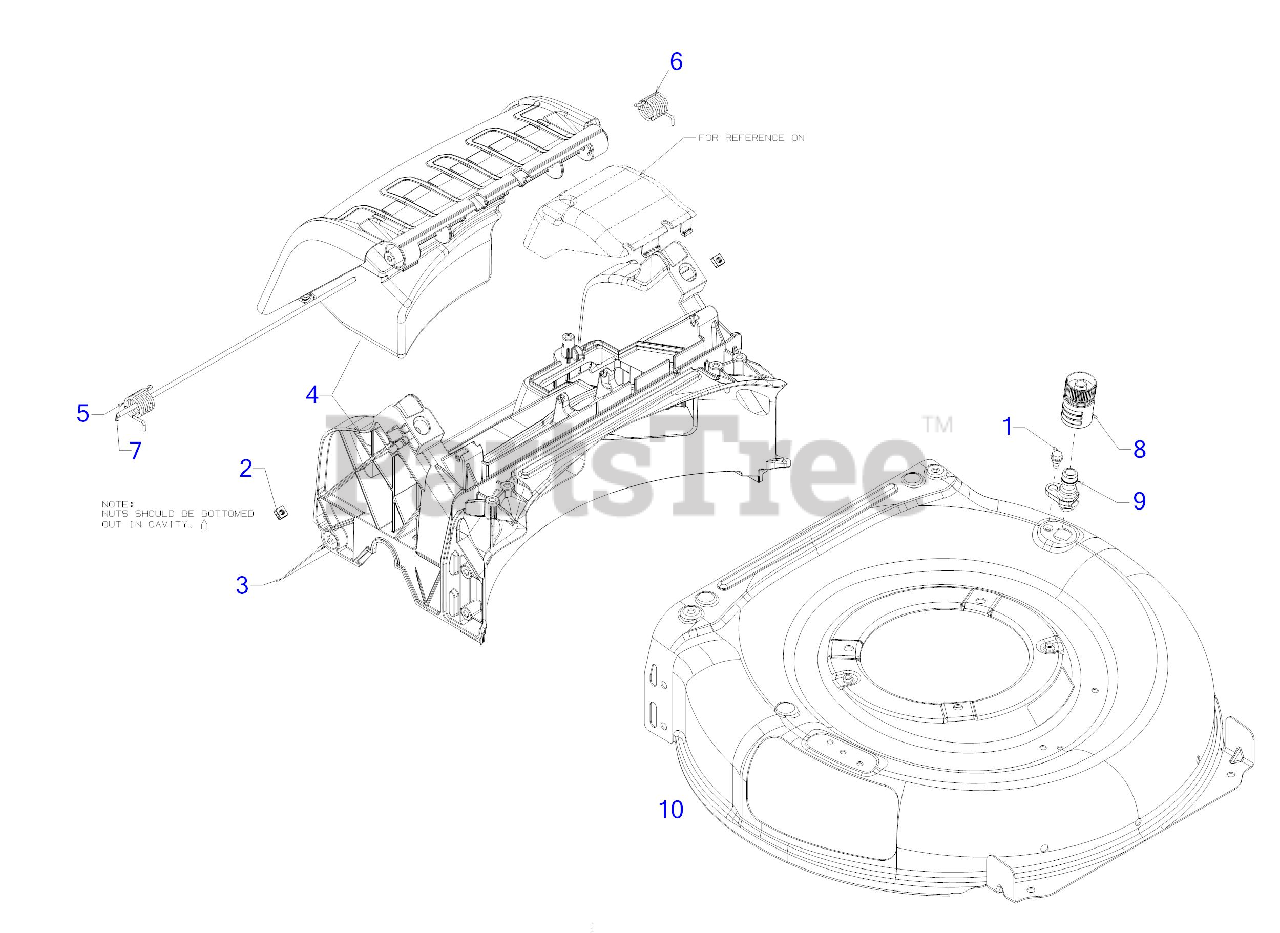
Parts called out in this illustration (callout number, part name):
1	SHOULDER SCREW 1/4-20 x .50
2	SQUARE NUT 1/4-20
3	TRAILSHIELD
4	REAR BAG BAFFLE ASSEMBLY
5	TORSION SPRING (RH)
6	TORSION SPRING (LH)
7	REAR DOOR PIVOT ROD
8	WATER NOZZLE
9	DECK WASH NOZZLE
